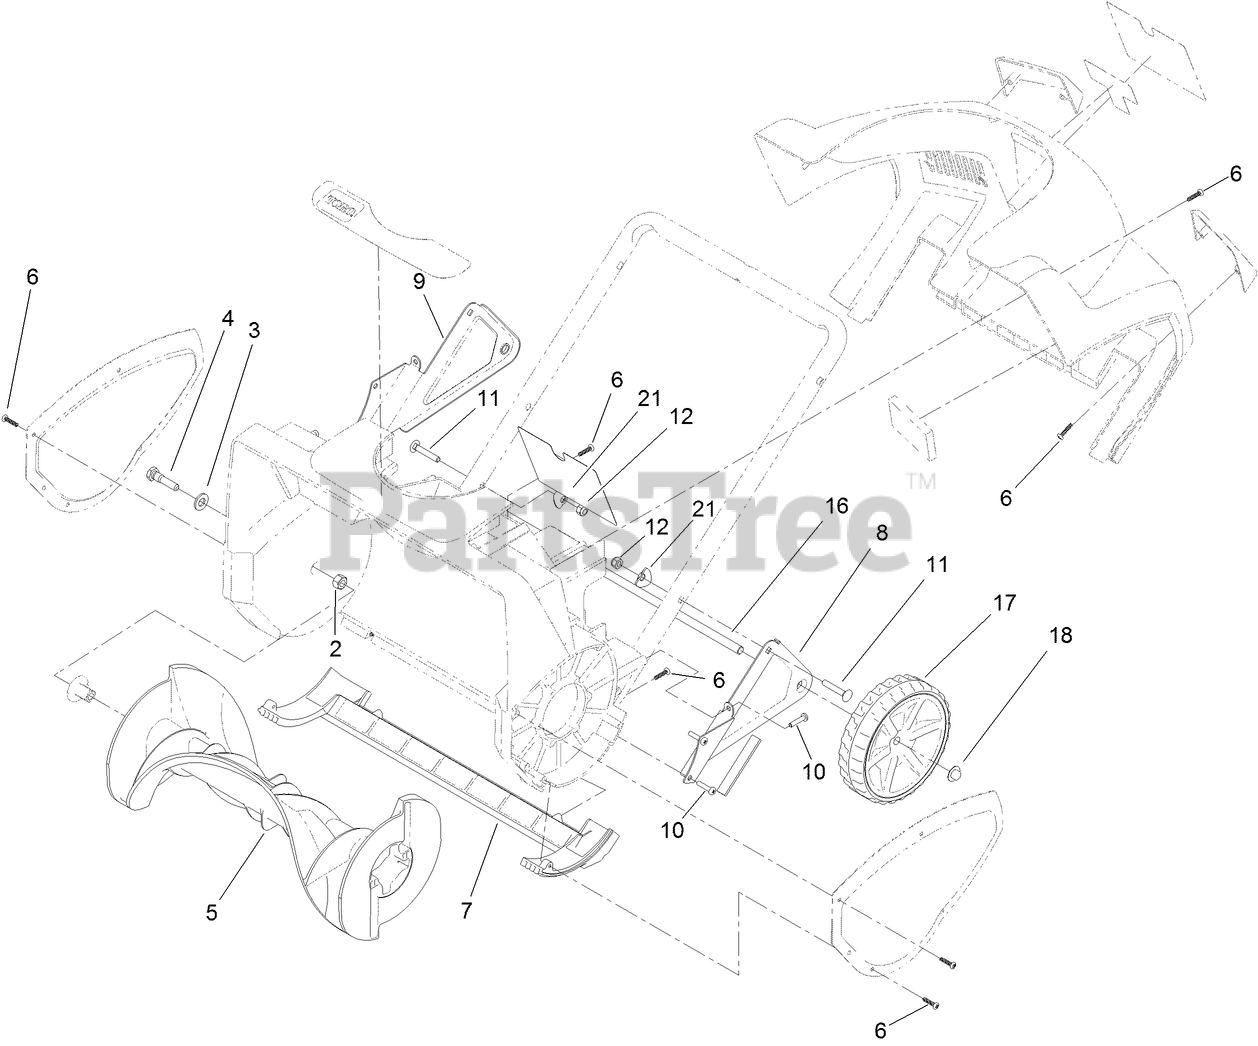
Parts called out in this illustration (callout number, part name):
3	WASHER-PLAIN
4	PIN-ROTOR
5	ROTOR ASM
6	SCREW-PPH
8	BRACKET-WHEEL, LH
9	BRACKET-WHEEL, RH
10	SCREW-PPH
11	SCREW-CARR
12	NUT-LOCK, NI
17	WHEEL ASM
